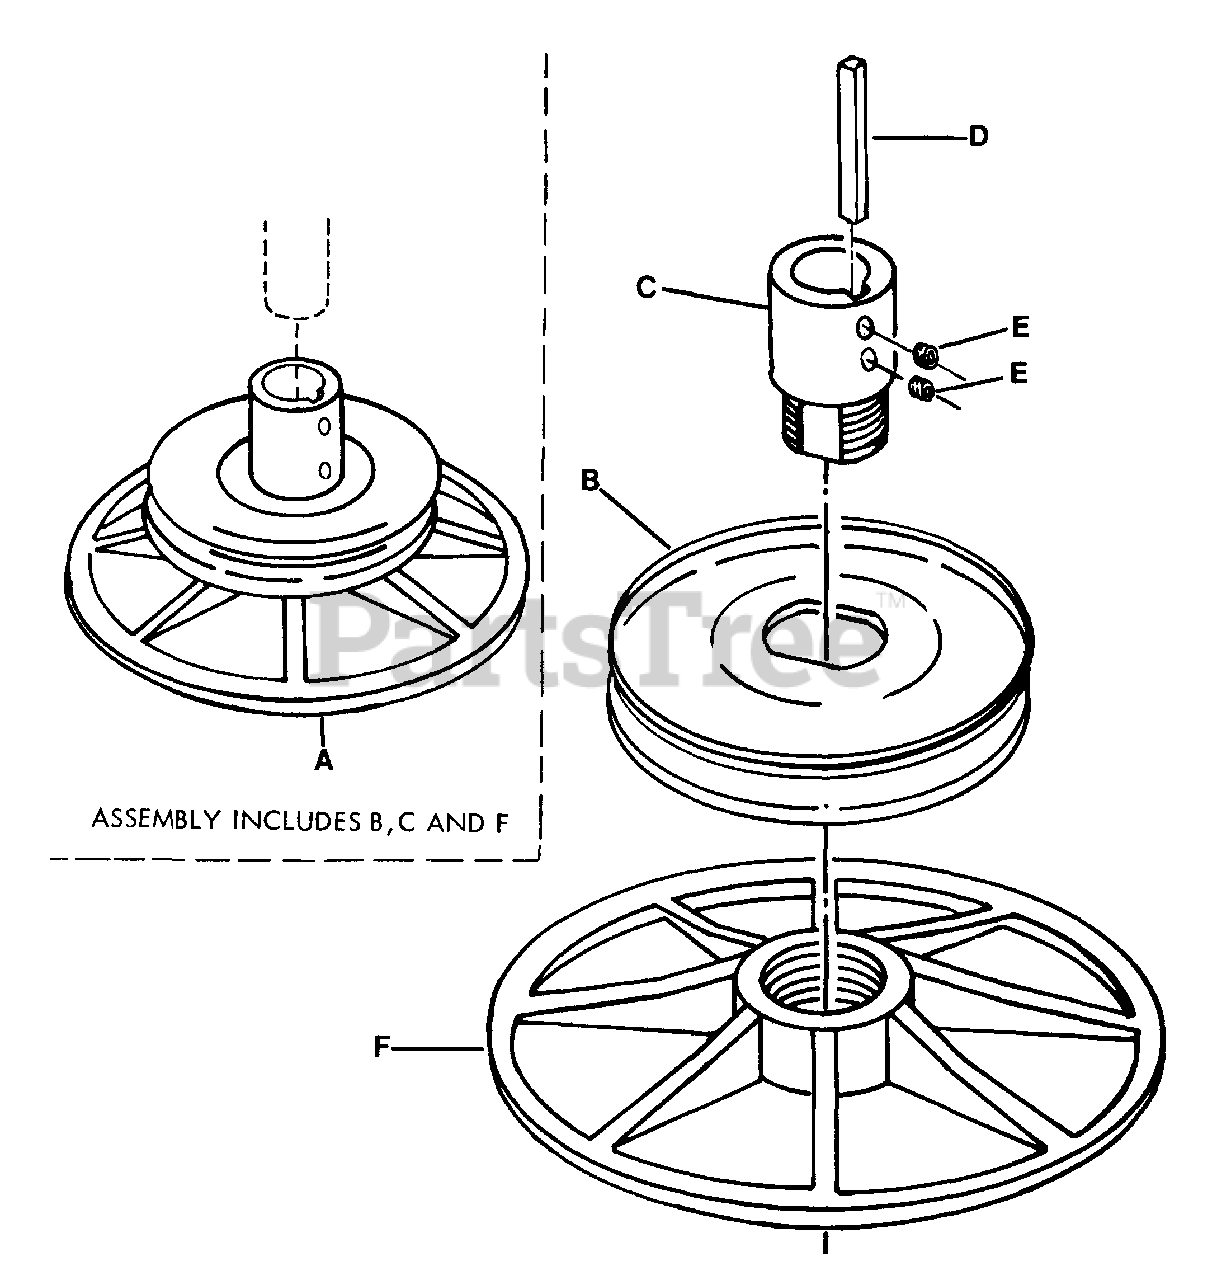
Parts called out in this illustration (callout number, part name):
A	DRIVE DISC ASSY: 4" PD
B	PULLEY, Drive 5.75" O.D.
C	HUB
D	KEY
E	SETSCREW, 3/8-16 x 3/8
F	DRIVE - DISC.
